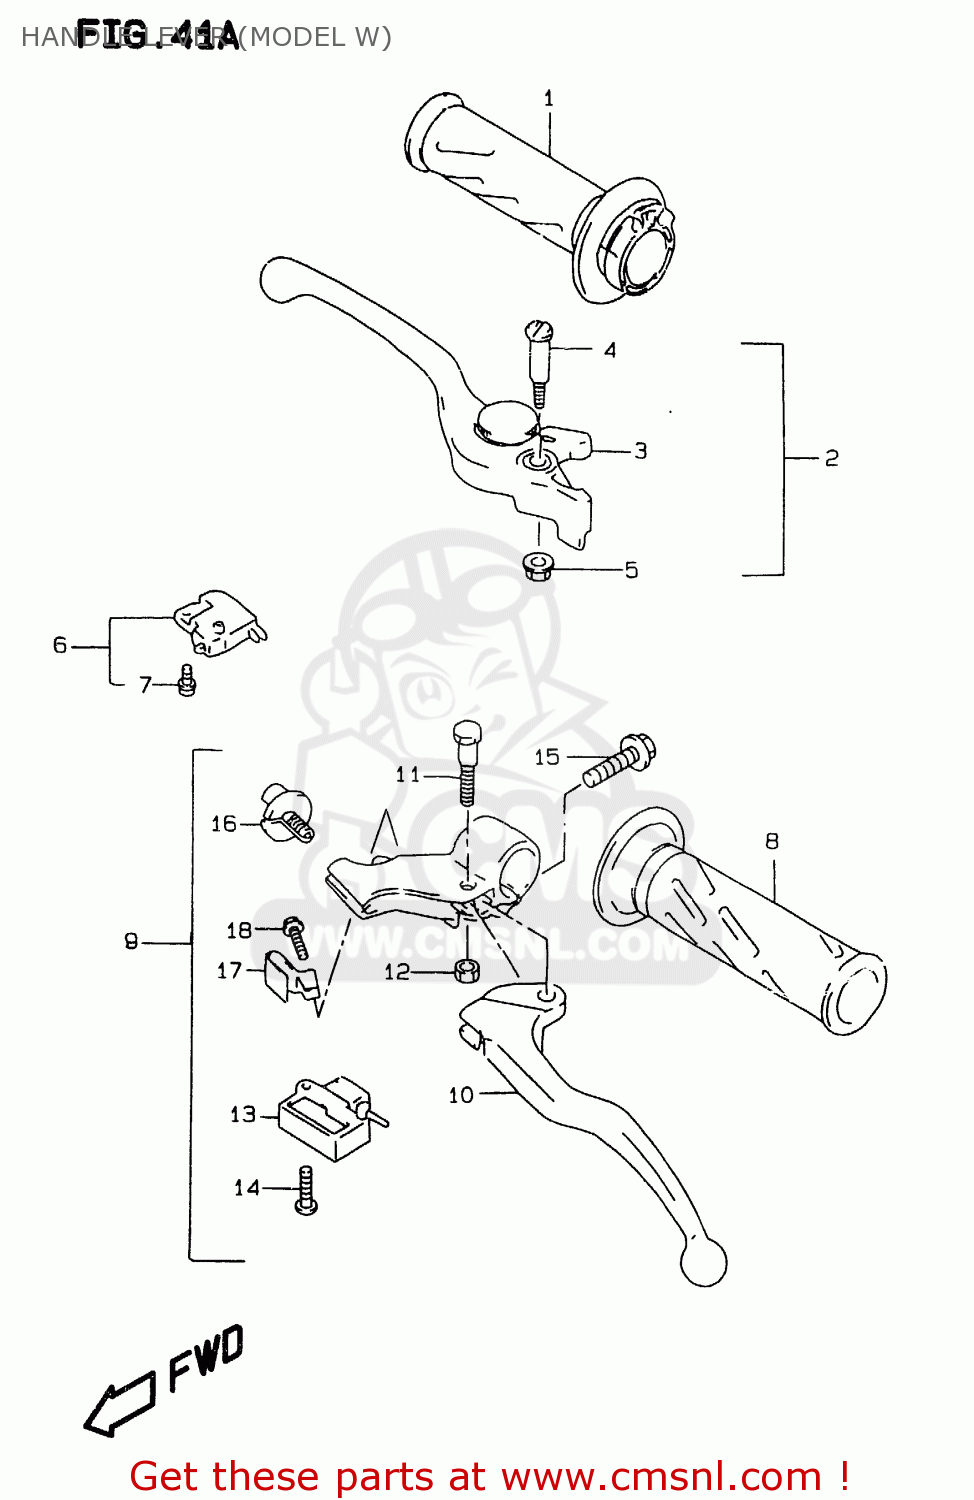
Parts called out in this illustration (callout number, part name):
1	GRIP,THROTTLE
2	LEVER ASSEMBLY,BRAKE
3	LEVER ASSEMBLY,ADJUST
4	BOLT,LEVER PIVOT
5	NUT
6	SWITCH ASSEMBLY,STOP
7	SCREW
8	GRIP,LEFT
9	LEVER ASSEMBLY,CLUTCH
10	LEVER,CLUTCH
11	BOLT,LEVER SET
12	NUT
13	SWITCH,CLUTCH
14	SCREW
15	SCREW
16	NUT,CABLE ADJUSTER
17	SPRING,ADJUST
18	SCREW,SPRING
